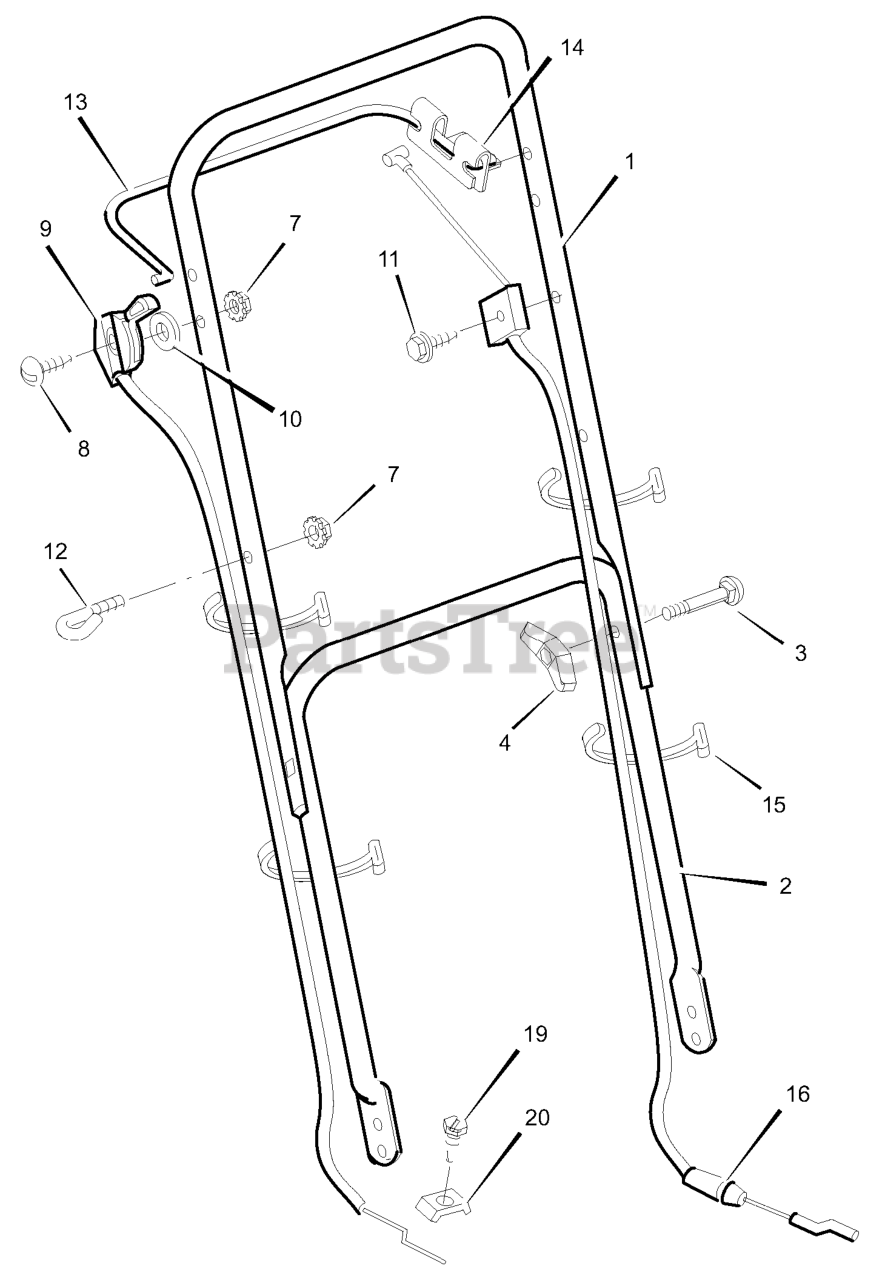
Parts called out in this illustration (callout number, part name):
1	Handle, Upper (Black)
2	Handle, Lower (Black)
3	BOLT, CRG .31-18 X 2
4	Wing Knob, 5/16-18
7	NUT.25-20 HEX NYLOCK
9	CABLE
10	WASHER ARDS
12	GUIDE-ROPE
13	Engine Stop Lever
14	Bracket, Stop Lever
15	TIE,STRAP-REMOVABLE, CONTAINS 10 PCS
16	S-CBL-S 39.00 22P C&
19	SCREW #10 32 NFX 62
20	Clamp, Throttle
